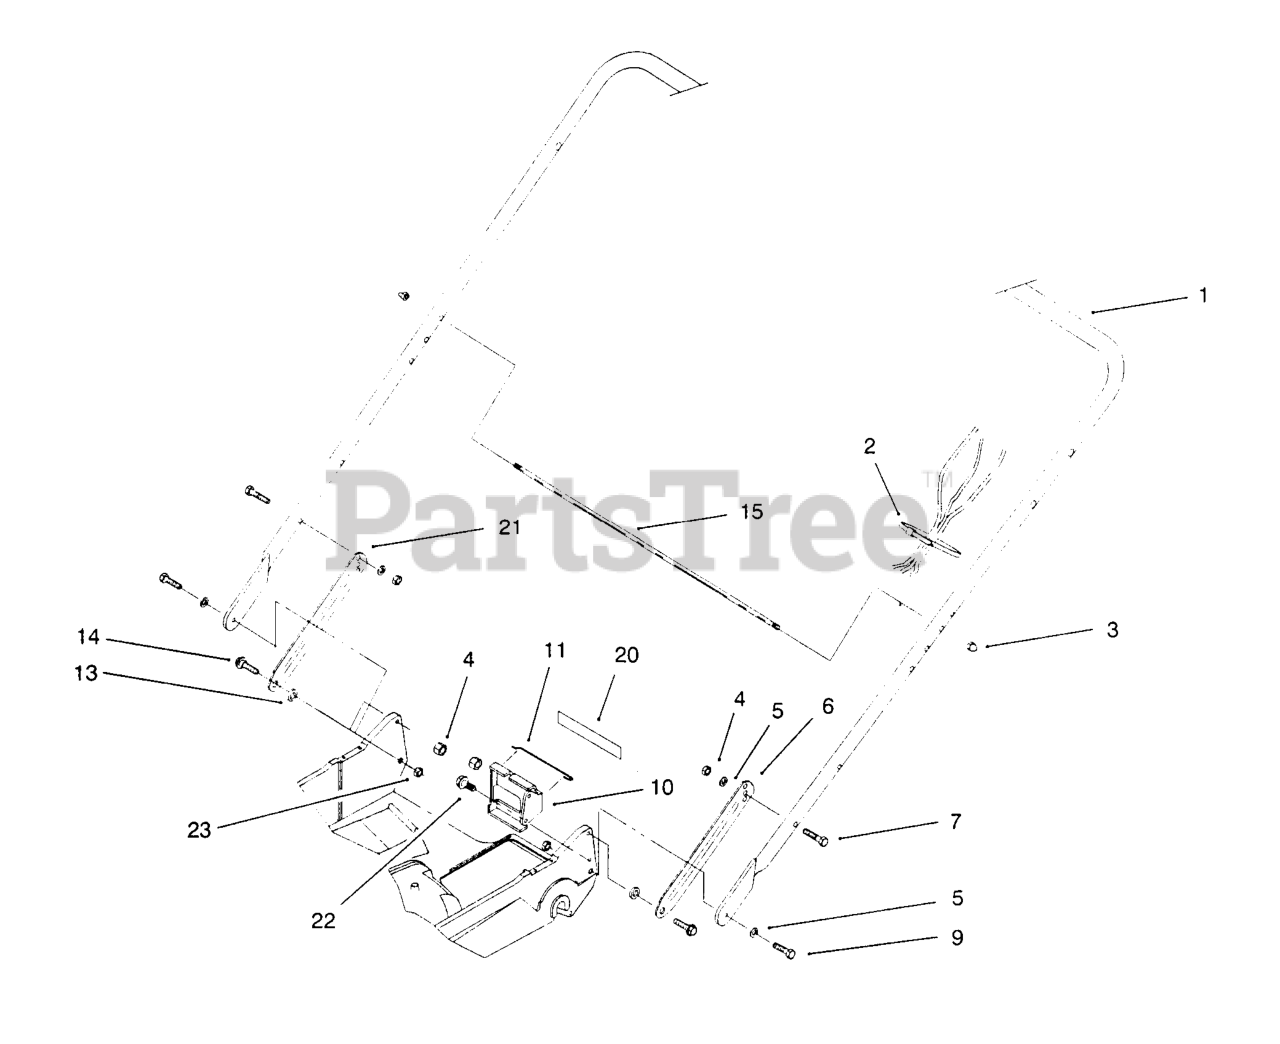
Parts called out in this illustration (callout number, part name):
2	TIE-CABLE
3	NUT-CAP
4	NUT-LOCK, NI
5	WASHER-BELLEVILLE
6	LATCH-HANDLE, LH
7	SCREW-HH
9	SCREW-HH
11	RETAINER-CABLE
13	SPACER
14	SCREW-SHOULDER
15	ROD-SUPPORT, BAG
20	DECAL-POSITION, GEAR
21	LATCH-HANDLE, RH
22	Screw-HWH 5/16-18 X 3/4 Tf
23	NUT-LOCK, NI
